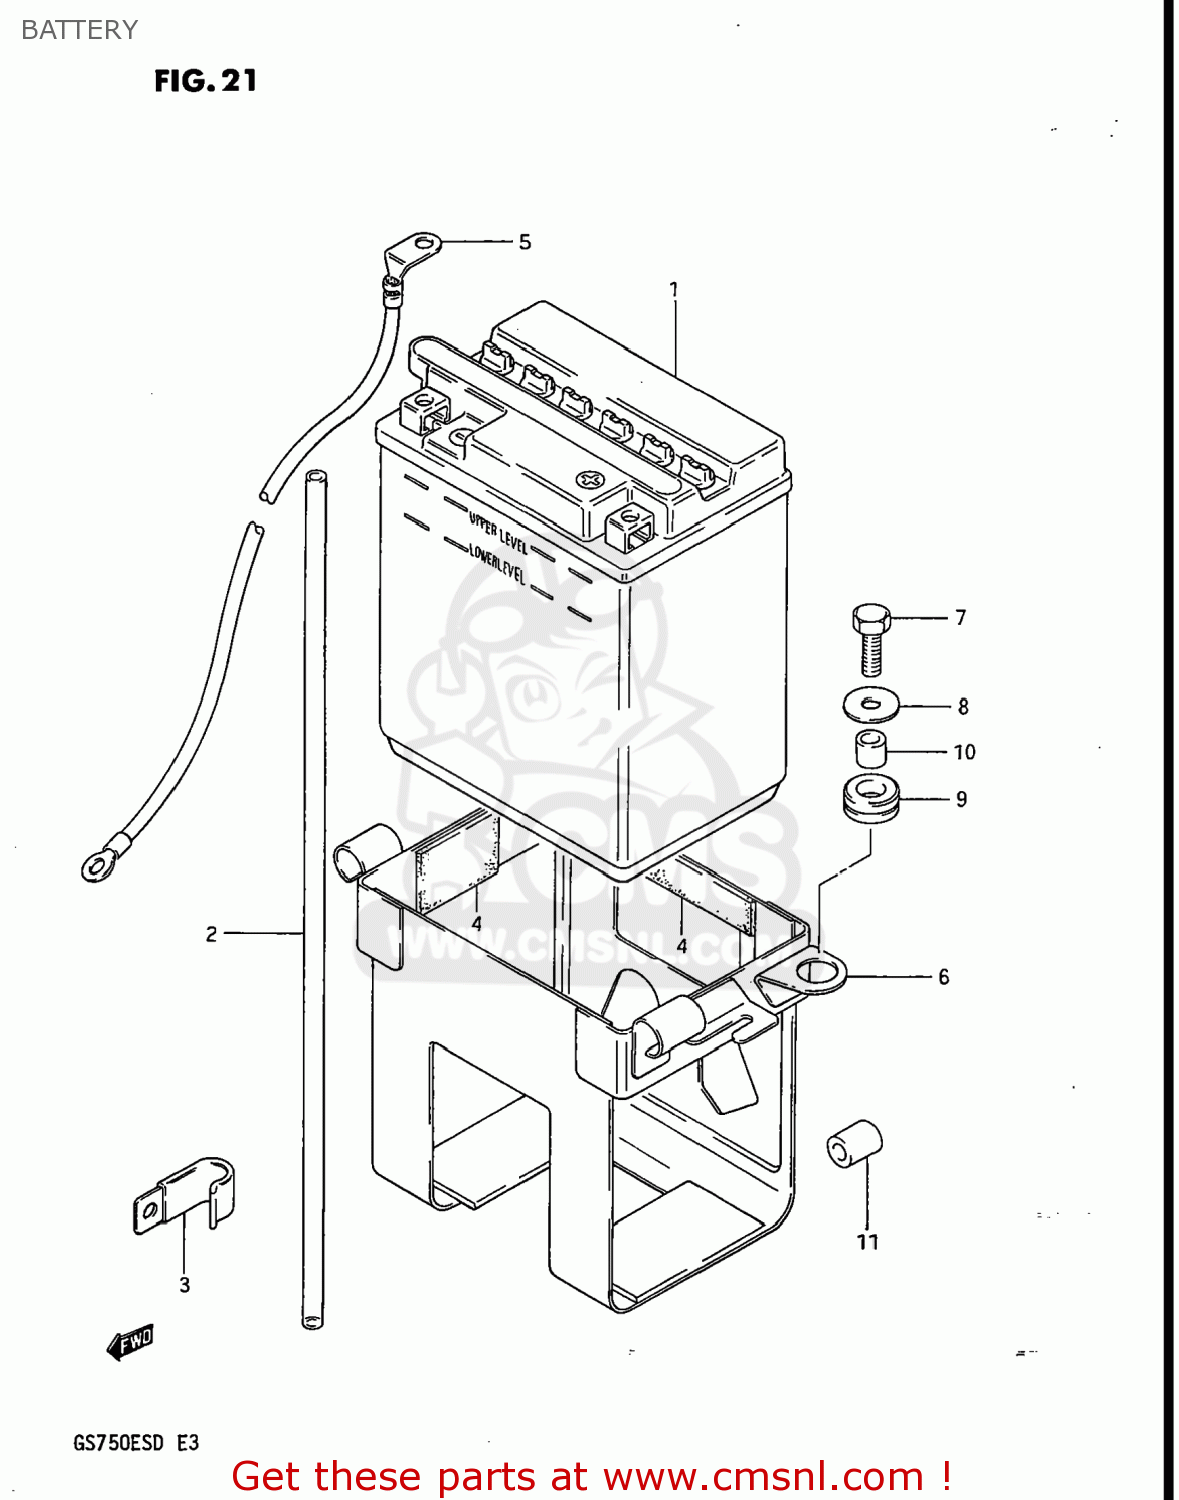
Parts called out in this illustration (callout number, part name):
1	BATTERY ASSY (12V)
2	HOSE,BATTERY EXHAUST
3	CLAMP
4	PROTECTOR(170X95X3.0)
5	WIRE,STARTER MOTOR LEAD
6	HOLDER,BATTERY
7	SCREW
8	WASHER (6.5X20X1.2)
9	CUSHION
10	SPACER(6.1X9X7.5)
11	CUSHION
